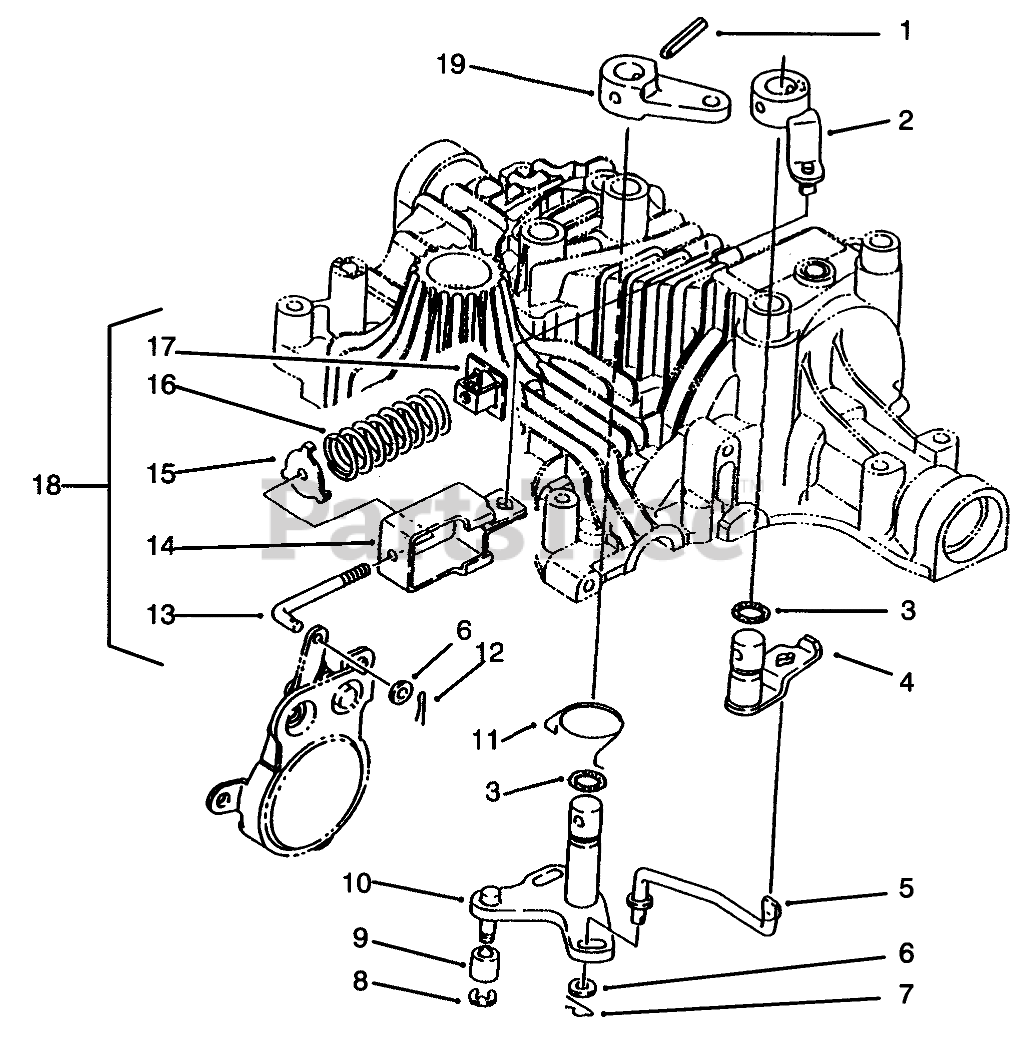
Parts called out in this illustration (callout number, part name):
1	Pin-Roll (Only On: 72043, 72063, 72103)
2	Arm-Brake B (Only On: 72043, 72063, 72103)
3	Packing (Only On: 72043, 72063, 72103)
4	Arm-Brake A (Only On: 72043, 72063, 72103)
5	Rod-Brake (Only On: 72043, 72063, 72103)
6	Washer (Only On: 72043, 72063, 72103)
7	Pin-Snap (Only On: 72043, 72063, 72103)
8	Ring (Only On: 72043, 72063, 72103)
9	Bushing (Only On: 72043, 72063, 72103)
10	Shaft-Brake (Only On: 72043, 72063, 72103)
11	Return-Brake (Only On: 72043, 72063, 72103)
12	Pin-Cotter (Only On: 72043, 72063, 72103)
13	Rod-Adjuster (Only On: 72043, 72063, 72103)
14	Holder-Spring (Only On: 72043, 72063, 72103)
15	Guide-Spring (Only On: 72043, 72063, 72103)
16	Spring (Only On: 72043, 72063, 72103)
17	Adjuster (Only On: 72043, 72063, 72103)
18	Rod ASM INCL 13-17 (Only On: 72043, 72063, 72103)
19	Arm-Brake (Only On: 72043, 72063, 72103)
